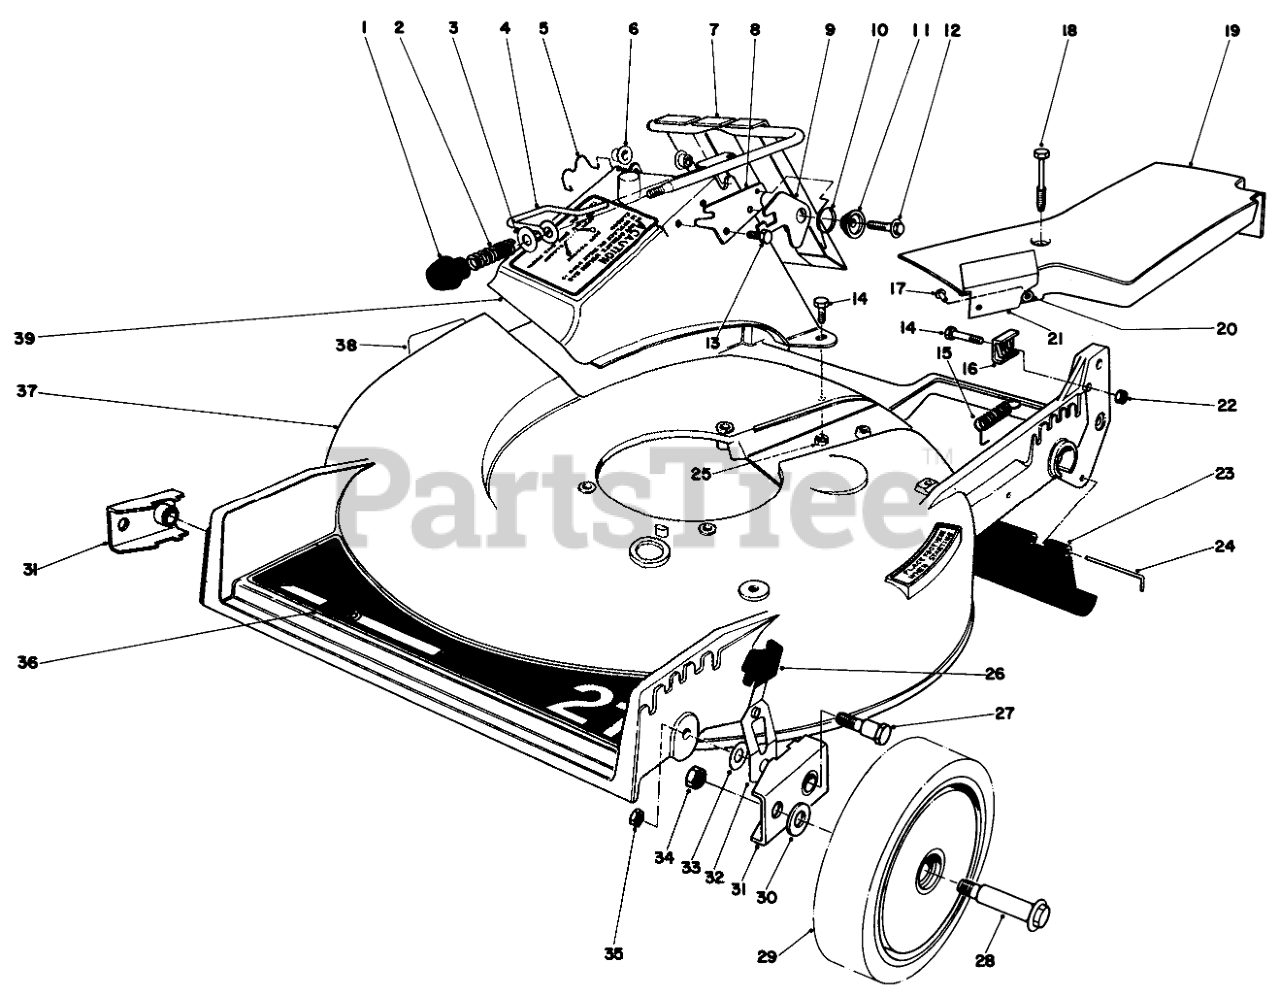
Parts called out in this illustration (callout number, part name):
2	COMPRESSION SPRING
3	WASHER-FLAT
4	DOOR LATCH
5	DOOR RETAINER
6	BUSHING-NYLON
7	DOOR & HANDLE WA
8	DOOR LATCH PLATE
9	SAFETY LATCH
10	TORSION SPRING
11	DOOR SPACER
12	Screw
13	SCREW-HWH
14	SCREW-HH
15	IDLER SPRING
16	CLAMP-CABLE
17	RIVET-HEAD, FLAT
18	SCREW-HHFTF
19	Belt Cover (Incl. Ref. #17 & 20-21)
20	WASHER-FLAT
21	HEAT SHIELD
22	NUT-JAM
23	SHIELD-TRAILING
24	ROD-SHIELD
25	NUT-LOCK, NI
26	KNOB-ARM
27	PIVOT SCREW
28	BOLT-WHEEL
29	Wheel & Tire Assembly
30	WASHER
31	Pivot Arm
32	Spring Arm
33	WASHER-PIVOT
34	Nut
35	Nut
36	DECK DECAL
37	Housing (Incl. Ref. #38)
38	DECAL-DANGER
39	DISCHARGE CHUTE B
